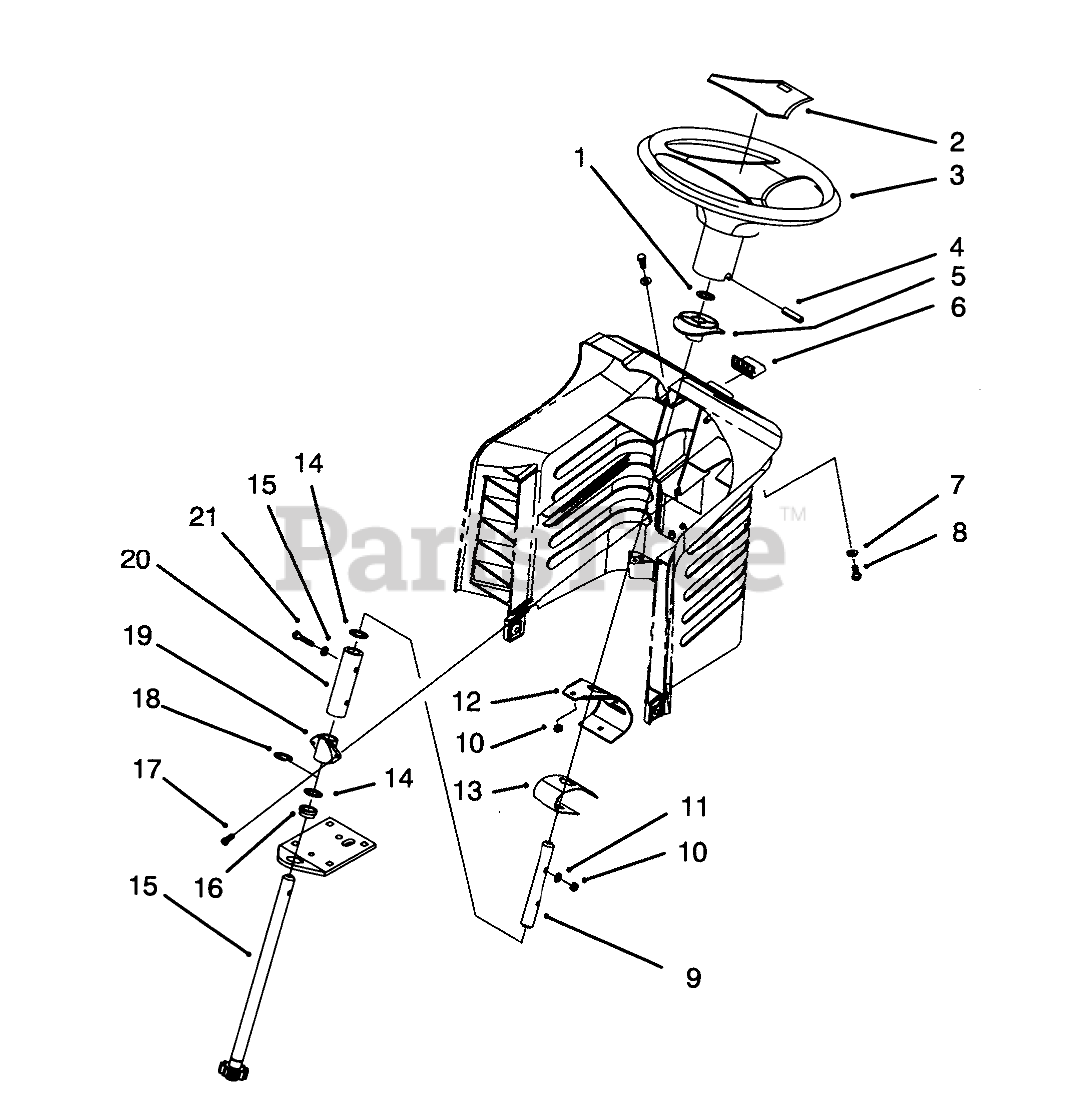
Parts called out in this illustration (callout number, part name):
1	PUSH-ON RETAINING RING
2	COVER-WHEEL
3	Wheel-Steering (Incl. Ref. #2)
4	PIN-ROLL
5	BUSHING-SLIDING
6	RELEASE BUTTON
7	WASHER-FLAT
8	SCREW-HH
9	UPPER STEERING SHAFT
10	NUT-LOCK, NI
11	WASHER
12	BACKUP BRACKET
13	SPRING LEAF
14	WASHER-THRUST
15	SHORT STRG SHAFT WA
16	BEARING-FLANGE
17	SCREW-SPECIAL
18	E-RING
19	BUSHING STATIONARY
20	COUPLING, STEERING
21	SCREW-HH
